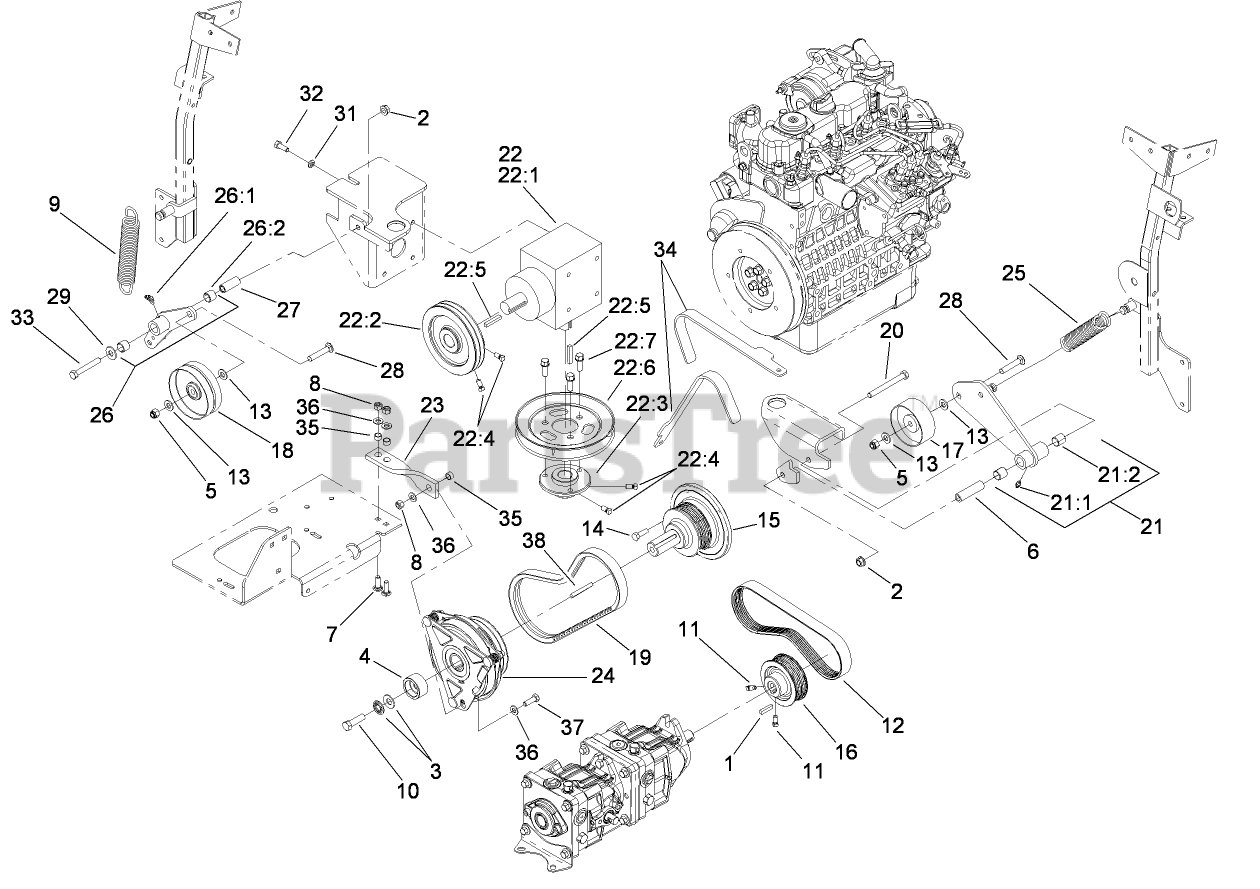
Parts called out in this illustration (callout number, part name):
2	NUT-HHF, WHIZ
3	WASHER-SPRING
4	RETAINER-CLUTCH
5	NUT-LOCK, NI
6	BUSHING-PIVOT, IDLER
7	SCREW-CARR
8	NUT-LOCK, NI
9	SPRING-EXTENSION
10	SCREW-HH
11	SCREW-SET
12	BELT-V
13	WASHER-FLAT
14	SCREW-HH
15	SHAFT-STUB
16	PULLEY
17	PULLEY-FLAT
18	PULLEY-FLAT
19	BELT-V
20	SCREW-HH
21	PUMP IDLER ARM ASM
21:1	FITTING-GREASE
21:2	SLEEVE-BEARING
22	Gearbox ASM
22:1	GEARBOX-90 DEG
22:2	PULLEY
22:3	HUB-PULLEY
22:4	SCREW-SET
22:5	KEY-SQUARE
22:6	PULLEY-B SECTION
22:7	SCREW-HWH
23	STRAP-STOP, CLUTCH
24	CLUTCH-MAGNETIC
25	SPRING-EXTENSION
26	GEARBOX IDLER ASM (W/BEARINGS)
26:1	FITTING-GREASE
26:2	SLEEVE-BEARING
27	BUSHING
28	SCREW-CARR
29	WASHER-FLAT
31	WASHER-LOCK
32	SCREW-HH
33	SCREW-HH
34	TOOL-ALIGNMENT, PULLEY
35	SPACER
36	WASHER-PLAIN
37	SCREW-HH
38	KEY-SQUARE
